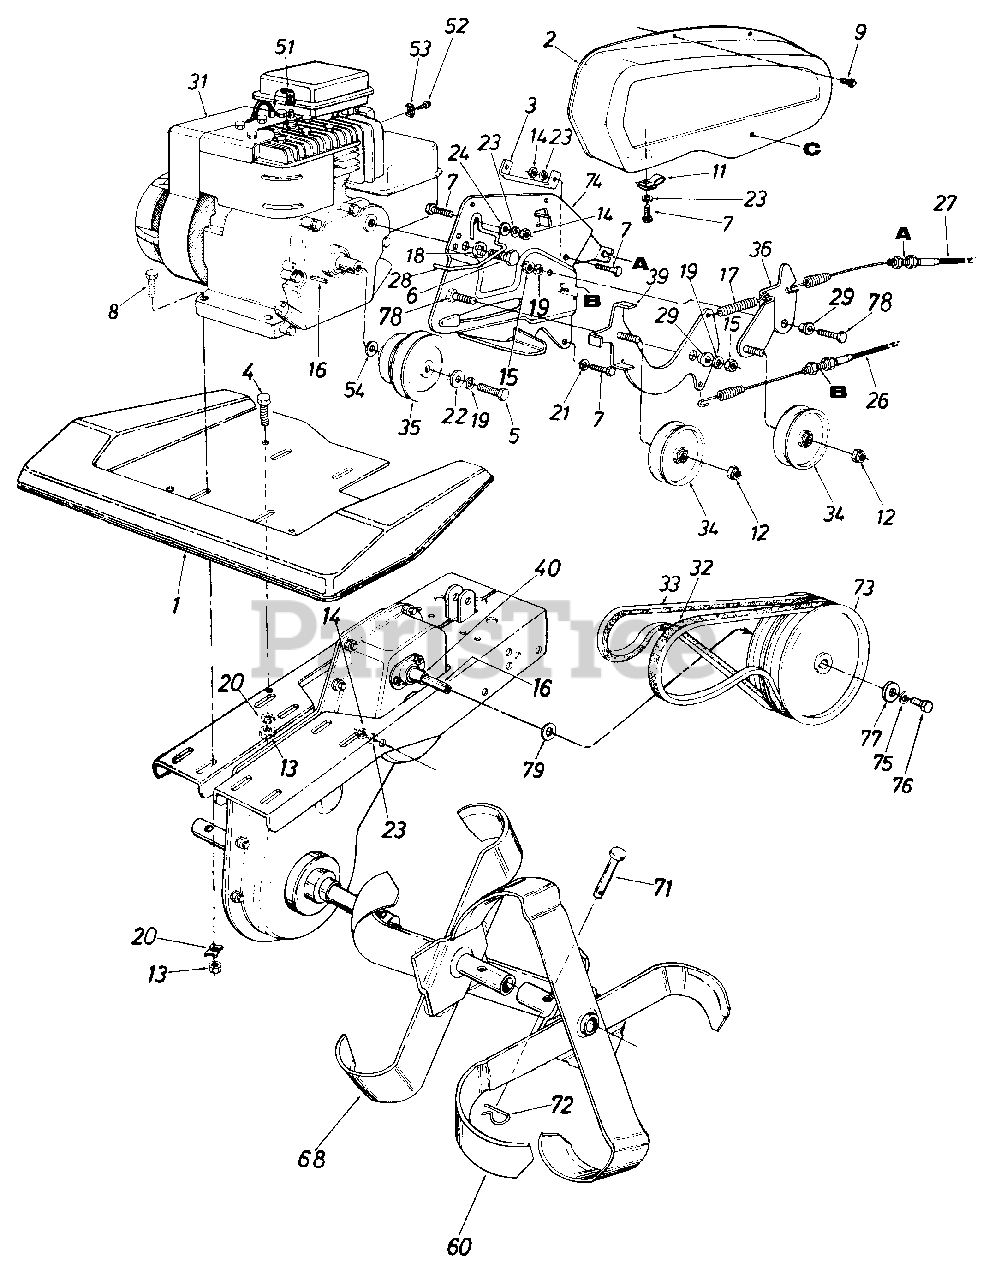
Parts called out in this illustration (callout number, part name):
4	Hex Bolt 5/16-18 x .75" Lg.*
5	Hex Bolt 3/8-24 x 1.25" Lg.
6	Hex Bolt 5/16-24 x .62" Lg.
7	Hex Bolt 1/4-20 x .85" Lg.
8	Hex Bolt 5/16-18 x 1.5" Lg.
9	Hex Wash. Hd. Tap Scr. 1/4-20 x .5" Lg.
11	Speed Nut 1/4-20 Thd.
12	Hex L-Nut 3/8-24 Thd.
13	Hex Nut 5/16-18 Thd.
14	Hex Nut 1/4-20 Thd.
15	Hex L-Nut 3/8-16 Thd.
16	Sq. Key 3/16 x 1.5" Lg.
17	Extension Spring 2.03 Lg.
18	L-Wash. 5/16" I.D.
19	L-Wash. 3/8" I.D.
20	Spec. L-Wash. 5/16" I.D.
21	Spr. Wash. .265" I.D. x .562" O.D.
22	Fl-Wash. 3/8" I.D. x 1" O.D. x 1.27"
23	L-Wash. 1/4" I.D.
24	Fl-Wash. .25.1.D. x .62 O.D.
26	Clutch Control Cable
27	Clutch Control Cable
28	Belt Guard Rod
29	Shld. Spacer .380 I.D.
31	Engine
32	V-Belt
33	V-Belt
34	Fl-ldler w/Flanges 3.12 O.D. x .75
35	Engine Pulley
40	Spacer .635 I.D.
51	Spark Plug Boot
52	Hex Sems Scr. #10-32 x .62" Lg.
53	Casing Clamp
54	Fl-Wash. .75" I.D. x 1.5" O.D. x .12"
72	Intern. Coter Pin
73	Transmission Pulley 6" Dia.
74	Clutch Mtg. Plate
75	L-Wash. 5/16" I.D.
76	Patch Bolt 5/16-18 x 1" Lg.
77	Fl-Wash. 5/16" I.D.
78	Hex Bolt 3/8-24 x 1.0" Lg.(Grade 5)
79	Fl-Wash. .635" I.D. x 1.25" O.D.
